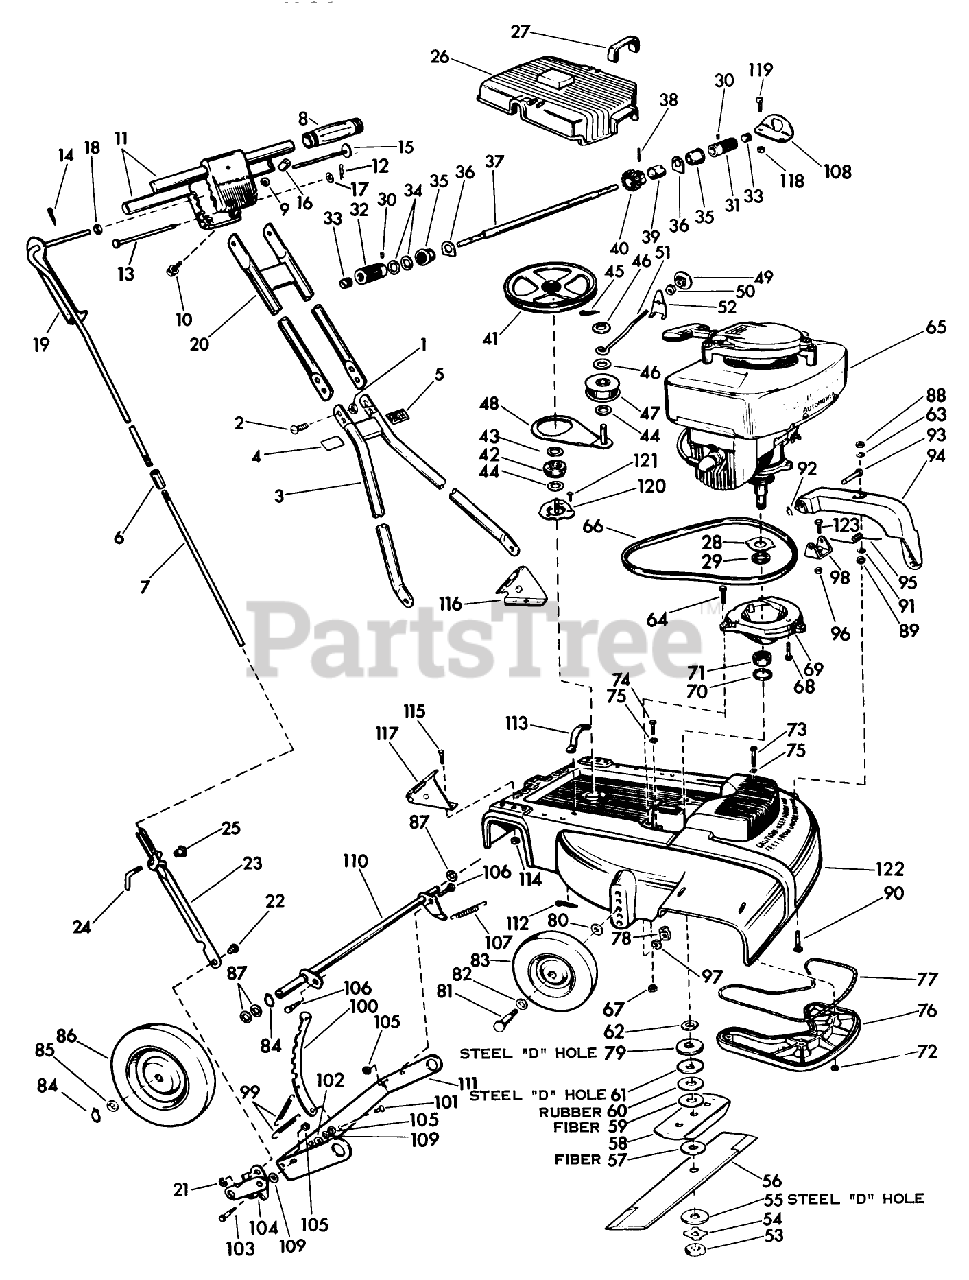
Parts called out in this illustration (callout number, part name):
1	STOP NUT
4	Decal-Handle "Low"
5	Decal-Handle "High"
9	Nut-Handle Bar Screw
11	Handle Bar Half
14	Pin-Cotter
17	Washer-Handle Pivot
18	Washer-Control Rod
26	Cover-Pulley, 18"
26	Cover-Pulley, 21"
28	Washer-Felt Seal Retainer
31	Roller-Drive Shaft, Left
33	GREASE PLUG
37	Drive Shaft, 18"
42	Felt-Oiler (Cup)
49	Knob-Speed Change
50	Nut-Lock
51	Rod-Speed Change
52	Lock-Speed Change
53	Nut-Blade
55	Washer-Steel "D" Hole
56	Blade-21"
60	BLADE WASHER
61	Washer-Steel "D" Hole
63	Washer-Level Ride, Fiber
66	Belt-V, 29" Class 3L, Fractional H.P. 18" Model
72	LOCKNUT E
73	Bolt-Muffler, Long
74	Bolt-Muffler
75	Gasket-Muffler Bolt
76	Muffler
79	Washer-Steel "D" Hole
84	RETAINING RING
88	STOP NUT
89	Nut-Level-Ride Bolt
90	Bolt-Level-Ride Arm
91	Washer-Level Ride Arm
92	Hair Pin-Level Ride Arm
93	Pin-Level Ride Arm
94	Arm-Level Ride
95	Spring-Level Ride Arm
96	STOP NUT
97	WASHER, LOCK
98	Bracket-Level Ride Arm
100	Lever-Height Adjustment
103	BOLT RB&W
105	STOP NUT
106	BOLT RB&W
109	WASHER S
111	Bracket-Axle, 18"
118	STOP NUT
123	Screw-Level-RideArm Bracket
